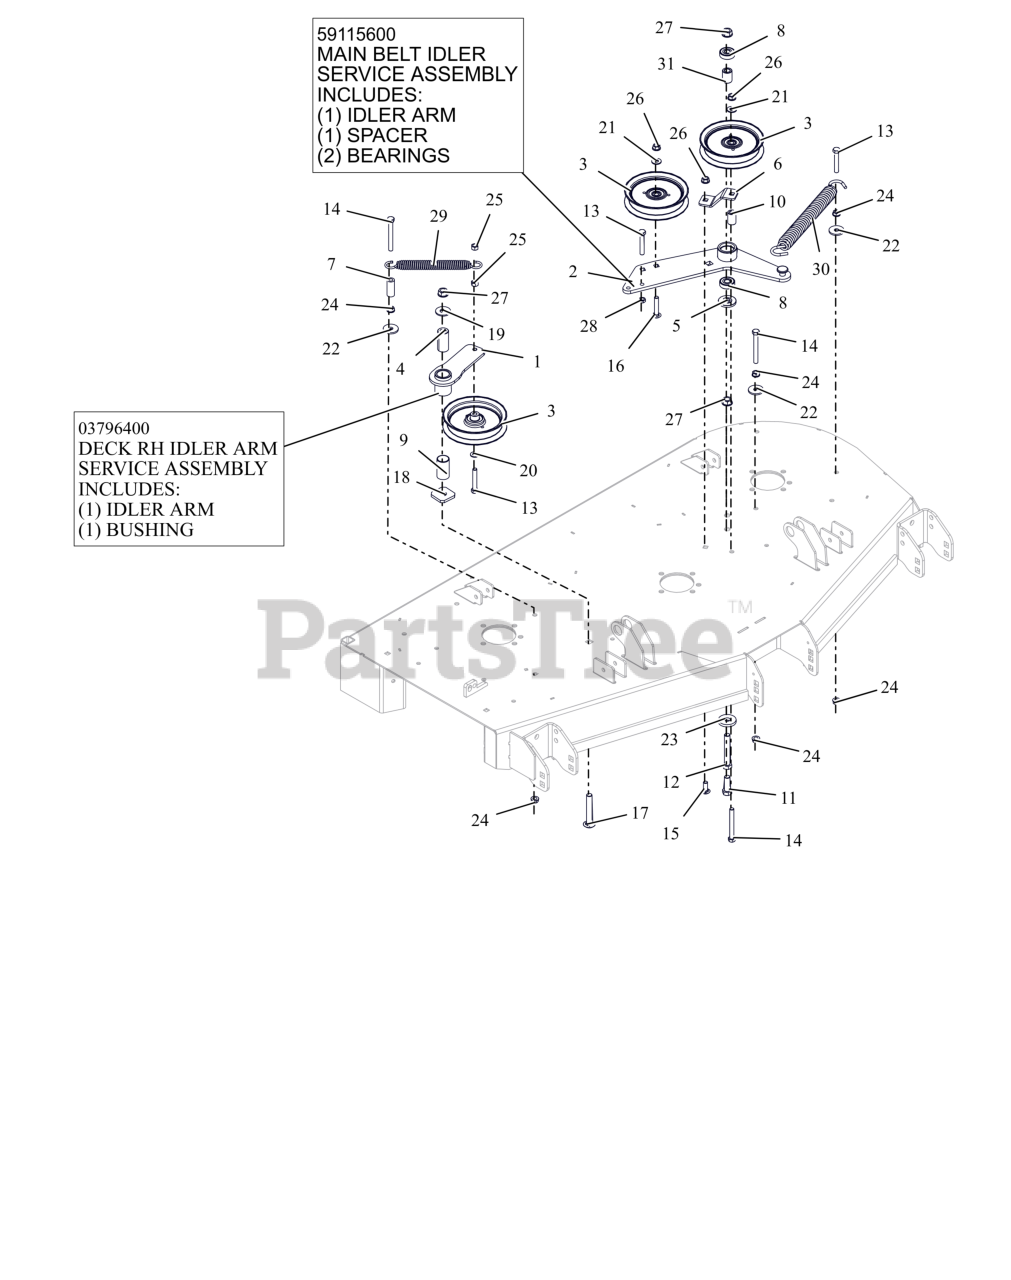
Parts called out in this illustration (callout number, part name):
1	WMT, IDLER ARM - BLACK
1	ASM, IDLER ARM (DECK)
2	WLDMT, DECK PTO IDLR ARM
2	ASSEMBLY, MAIN BELT IDLER
3	IDLER, FLAT 5.00"
4	BSHG, SPCR .502X.997X2.03 PM
5	SPACER, IDLER ARM
6	PTO FIXED IDLER MTG BRKT -RED
7	HOSE, .38 X 1.65
8	BRG-BALL .500X1.38X.437
9	BSHG, 1.00X1.125X1.937
10	BUSHING, SLV .380X.750X1.190
11	BLT,HEX .50-13X1.50 G5 ZCC
12	BLT,HEX .50-13X3.25 G5 ZCC
13	BLT,HEX .38-16X2.25 G5 ZCC
14	BLT, HEX .38-16X3.25 G5 ZCC
15	BLT,RHSSN .38-16X1.00 G5 ZCC
16	BLT,RHSSN.375-16X2.00 G5 ZCC
17	BTL,RHSSN .500-13 X 3.25 G5 ZCC
18	WSHR-FLT .640X1.75X.250
19	WSHR,FLT .563X1.375X.109 ZCC
20	WSHR,FLT .406X.812X.065 ZCC
21	WSHR,FLT .375X.875X.083 ZCC
22	WSHR,FLT .406X1.375X.135 ZCC
23	WSHR-FL-STL 0.557X1.625X0.25 ZCC
24	NUT, SPNLK-FLG .38-16 G5 ZCC
25	NUT-LK-CTR .38-16 ZC120
26	NUT-LK-CTR-FLG .375-16 GF ZCC
27	NUT-LK-CTR-FLG .500-13 GG ZCC
28	NUT-JAM .375-16 G2 ZCC
29	SPRING, EXTENSION
30	SPRING, EXTENSION
31	SPACER .510 X .75 X 1.1485
